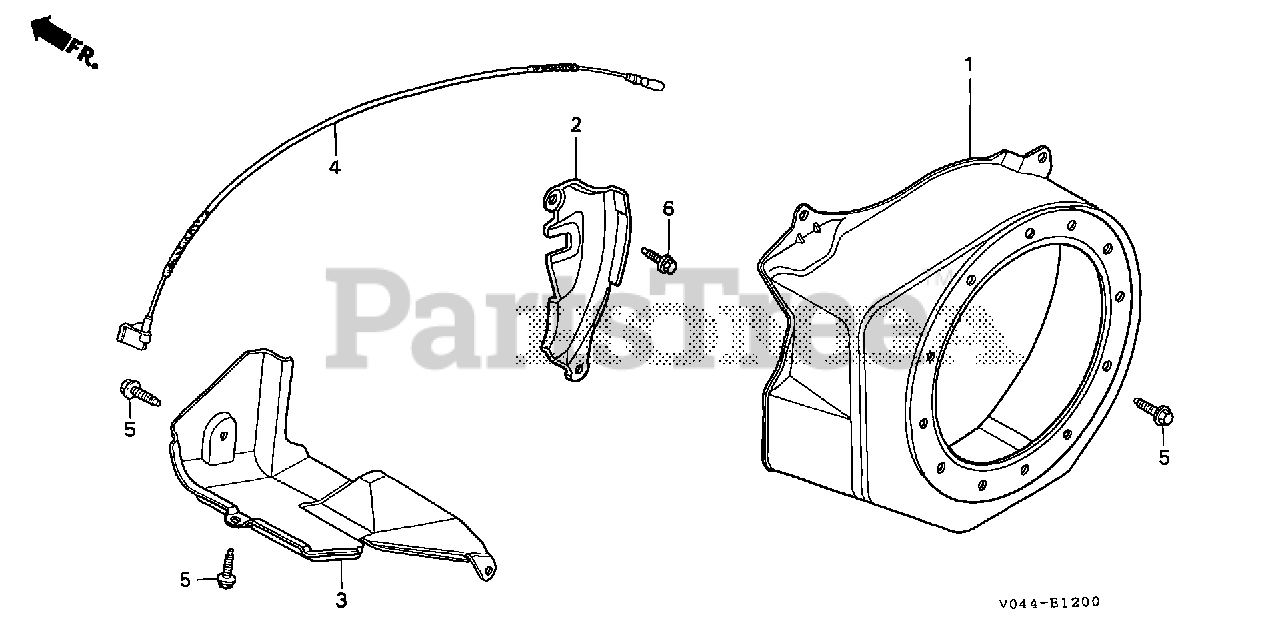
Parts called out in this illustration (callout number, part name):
1	COVER, FAN *R280* (POWER RED)
2	PLATE, SIDE (LAMP)
3	SHROUD
4	WIRE, STOP SWITCH (370MM)
5	BOLT, FLANGE (6X12) (CT200)
6	BOLT, FLANGE (6X20) (CT200)
